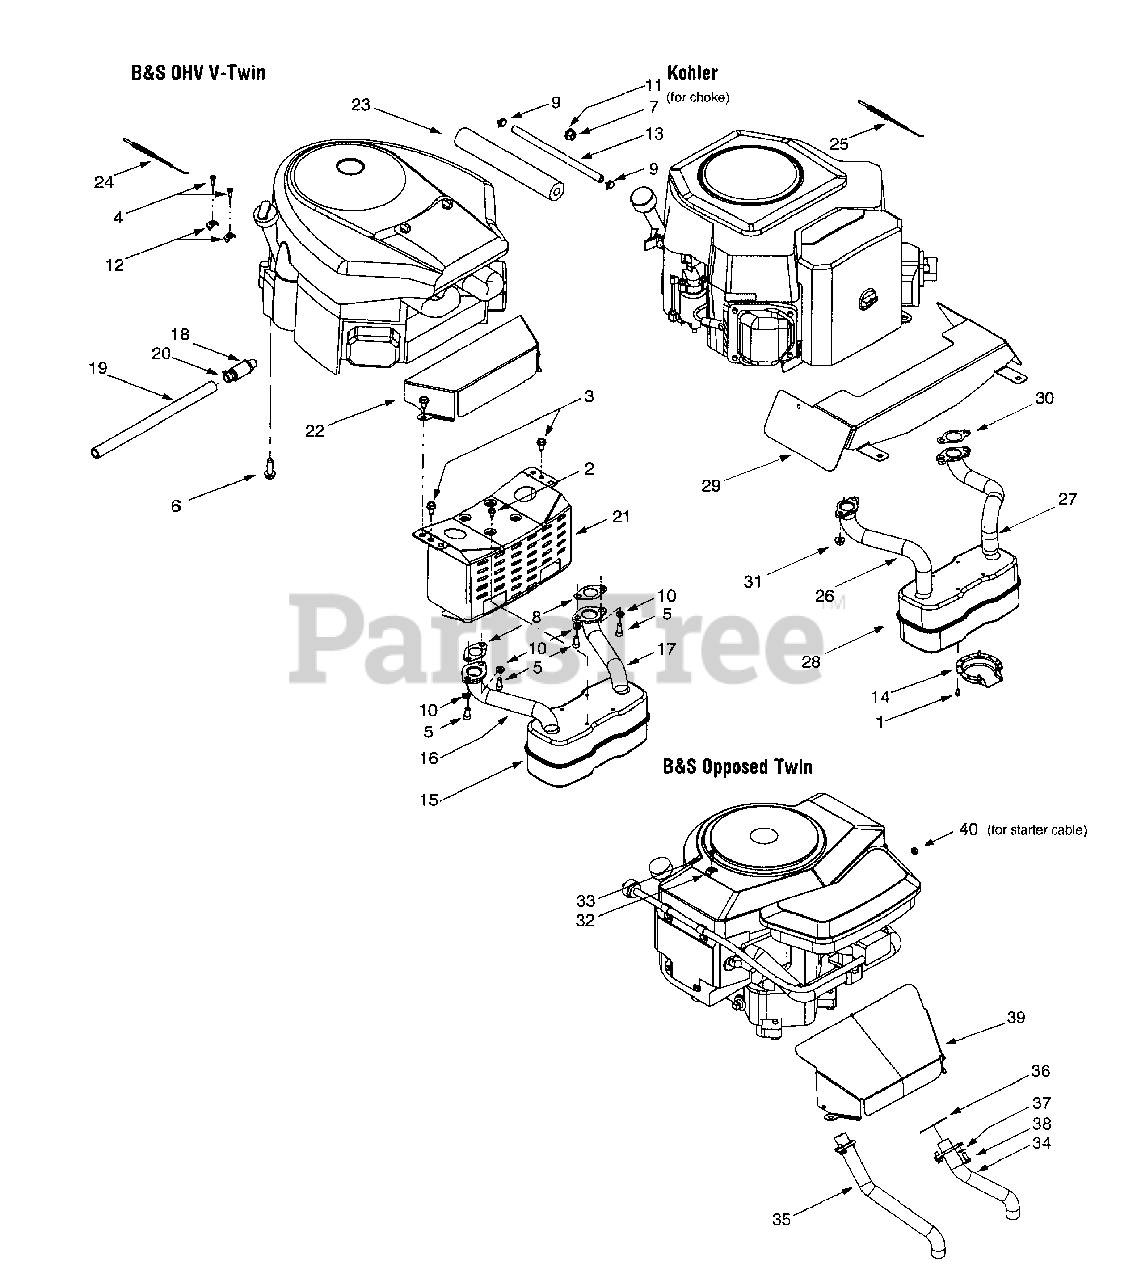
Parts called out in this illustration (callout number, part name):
1	Self-tapping Screw, #8-18 x .5
2	Self-tapping Screw, 1/4-20 x .5
3	Self-tapping Screw, 5/16-18 x .625
4	Screw, #10-32 x .625
5	Socket Cap Screw, 5/16-18 x .625
6	Self-tapping Screw, 3/8-16 x 1.25
7	Hex Nut, 3/8-16
8	Exhaust Gasket
9	Hose Clamp
10	Lock Washer, 5/16
11	Flat Washer
12	Casing Clamp
13	Fuel Line Hose
14	Muffler Deflector
15	Muffler, Twin Inlet
16	RH Exhaust Pipe
17	LH Exhaust Pipe
18	Oil Drain Valve
19	Oil Drain Hose
20	Oil Drain Cap
22	Engine Heat Shield
23	Foam (fits over fuel line)
24	Throttle Cable
25	Throttle Cable
26	RH Exhaust Pipe
27	LH Exhaust Pipe
28	Muffler, Twin Inlet
29	Engine Heat Shield
30	Exhaust Gasket
31	Flange Nut, M8 x 1.25-6
32	Clamp, 9/16
33	Screw, #10-16 x .5
34	LH Exhaust Pipe
35	RH Exhaust Pipe
36	Exhaust Gasket
37	Lock Washer, 1/4
38	Hex Screw, 1/4-20 x .620
40	Hex Sems Nut, 1/4-20
